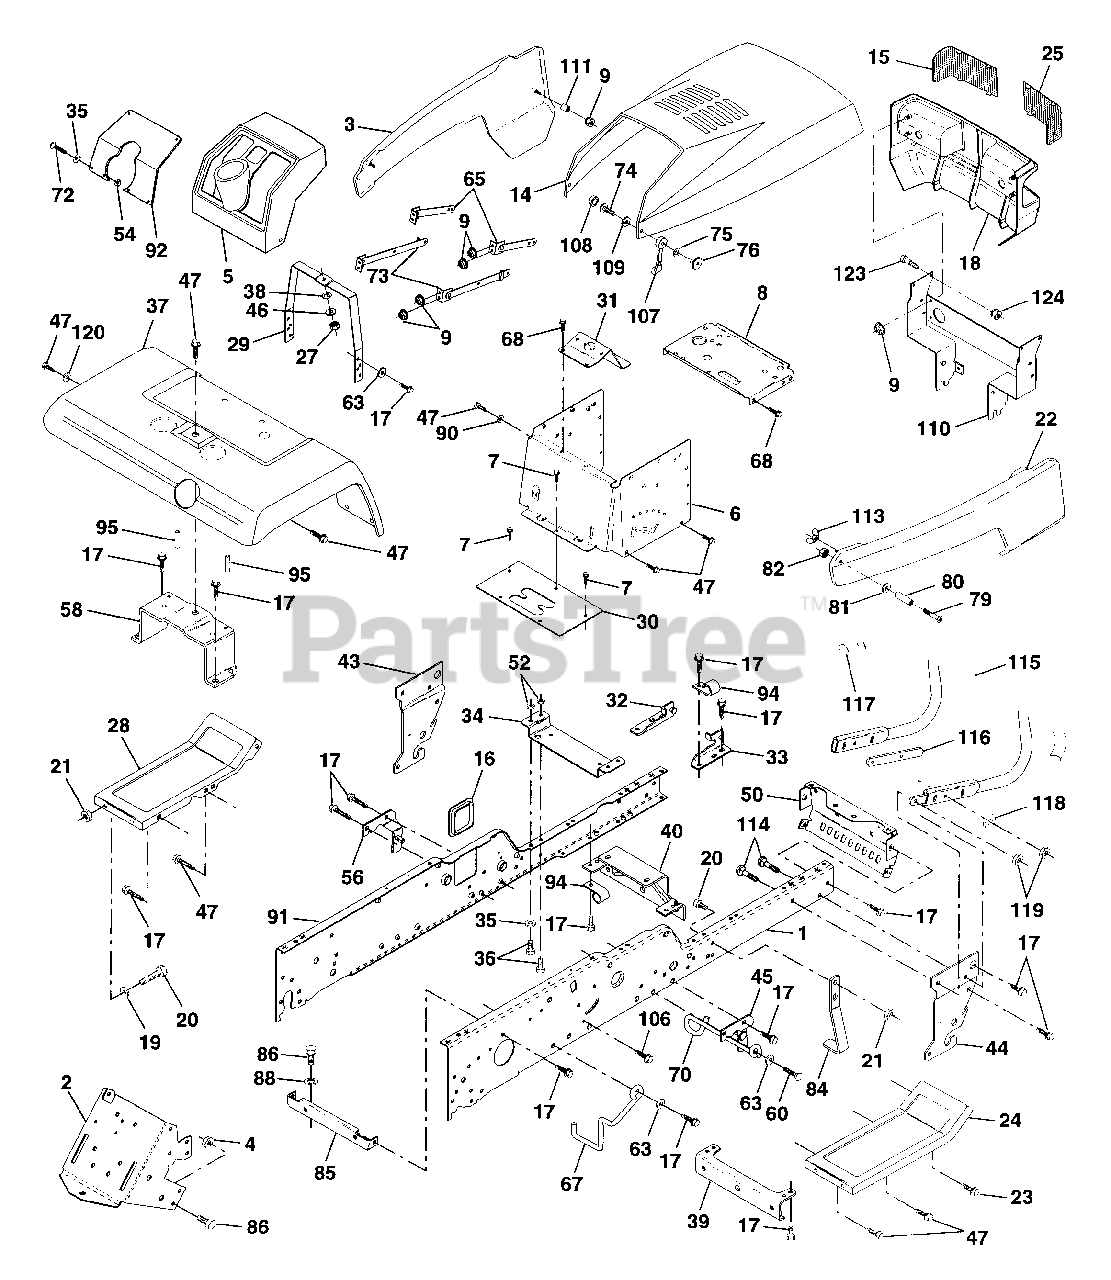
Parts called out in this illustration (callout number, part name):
1	Rail, Frame RH
2	Drawbar, Gt
3	Panel Asm., Side LH
4	Nut, Crownlock 7/16-14 Unc
5	Dash, Plastic Black
6	Dash 1-Pcs., Lower
7	Screw, Thd Cut 1/4-20 x 1/2
8	Support, Battery
9	UNKOWN
14	Hood Asm., Pnt
15	Lens, Headlight LH
16	Cover, Access
17	Screw, Thdrol 3/8-16 x 3/4
18	Grille
19	Washer 13/32 x 13/16 x 12 Ga.
20	Bolt, Fin Hex 3/8-16 x 1
21	Nut, Crownlock 3/8-16 Unc
22	Panel Asm., Side RH
23	Screw, Thdrol. 3/8-16 x 1 Ty-Tt
24	Footrest, RH
25	Lens Headlight RH
27	Nut, Fin Hex 1/4-20
28	Footrest, LH
29	Bracket, Support Dash
31	Bracket, Support Steering
32	Bracket Asm., Frame Pivot Lh
33	Bracket Asm., Frame Pivot Rh
34	Bracket, Engine Support Rear
35	Washer 11/32 x 11/16 x 16 Ga.
36	Bolt, Fin Hex 5/16-18 x 3/4
37	Fender, Pnt.
38	Washer, Lock 1/4
39	Bracket, Axle Front
40	Bracket, Support Axle/Engine
43	Bracket, Spnsn Front Lh
44	Bracket, Spnsn Front Rh
45	Bracket Asm., Susp Chassis Rh
46	Washer 9/32 x 3/4 x 16 Ga.
47	Screw Thdrol 3/8-16 x 1/2
50	Bracket, Chassis Front
52	Locknut, Hex W/Ins 5/16-18 Unc
54	Nut 5/16-18
56	Bracket Asm., Susp Chassis Lh
58	Bracket Asm., Fender
60	Screw Thdrol 3/8-16 x 1-1/4
63	Washer 13/32 x 3/4 x 14 Ga.
65	Strap, Asm. Hinge Front
67	Guide, Belt
68	Screw, Thdrol 5/16-18 x 1/2
70	Guide, Belt Mid Span
72	Screw, Mach Trhd 5/16-18 x 3/4
73	Strap, Asm. Hinge Rear
74	Screw, Machine #10-24
75	Washer, Lock #10
76	Nut, Weld #10-24
79	Screw, Machine #10-24 x 1/4
80	Spacer, Split
81	Washer 7/32 x 1/2 x 18 Ga.
82	Nut #10-24
84	Stop, Over Center Mower
85	Bracket, Support
86	Bolt, Fin Hex 7/16-14 Unc x 1
88	Washer, Lock Hvy Hld Sp 7/16
90	Washer, Lock External Tooth 3/8
91	Rail, Frame Lh
92	Plate, Silkscreen Dash
94	Clip, Fuel Line
95	Push Nut, Nylon
106	Bolt 5/16 - 18 Type TT
107	Latch, Chute Blk
108	Cap, Snap Black
109	Cap, Washer Snap
110	Support Asm. Grille
113	Nut, Plastic Locking Wing 1/4-20
114	Bolt, Carriage 3/8-16 x 1-1/4
115	Bumper Asm.
116	Bracket, Extension, Bumper
117	Plug, Plastic
118	Washer 13/32 x 13/16 x 16 Ga.
119	Nut Crownlock 3/8-16 UNC
120	Washer 13/32 x 1 x 16 Ga.
123	Bolt Shoulder 1/4-20
124	Nut, Lock W/Ins 1/4-20
